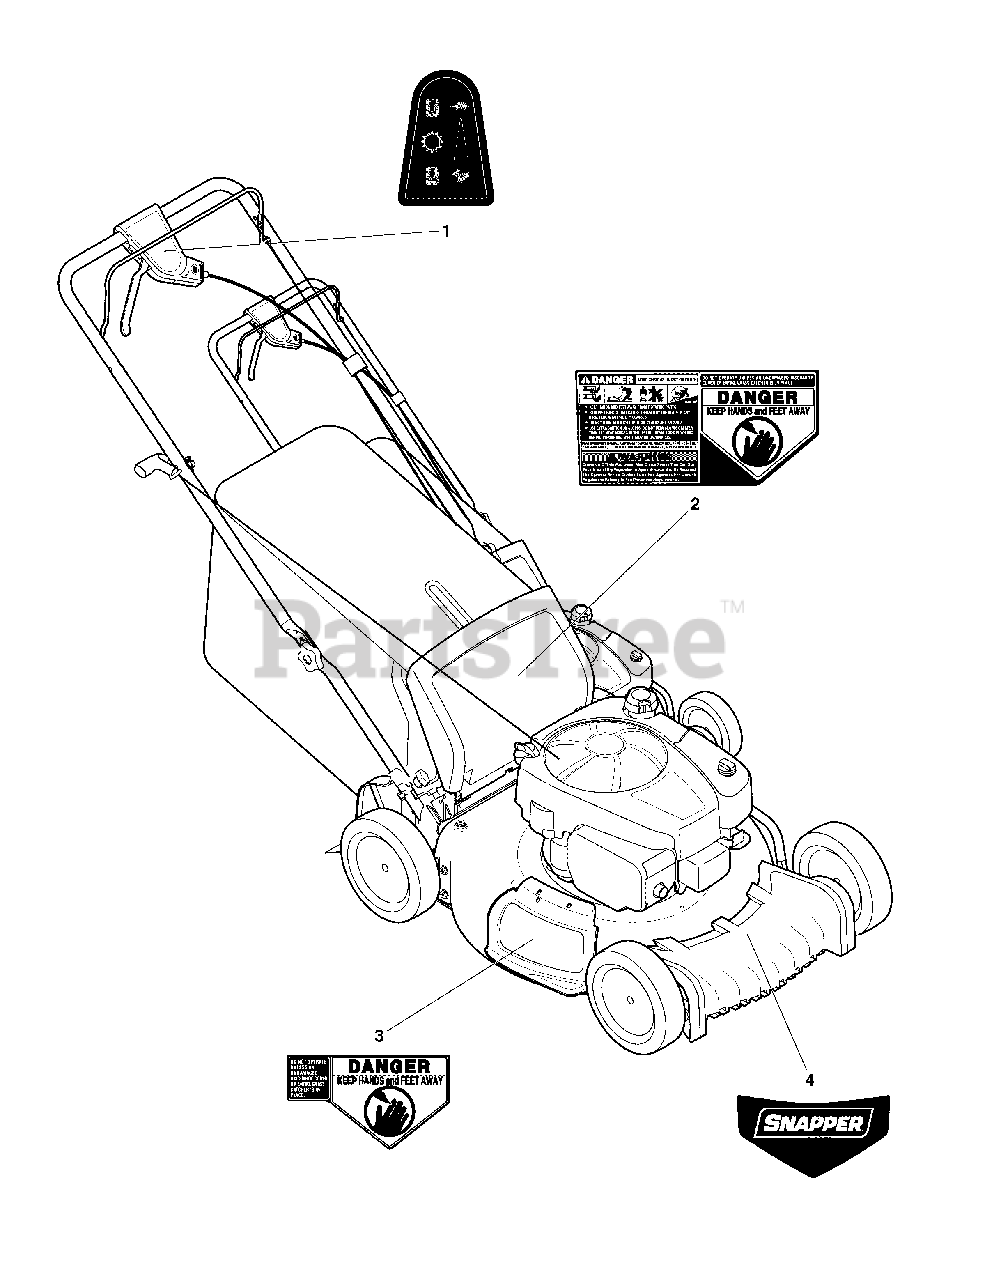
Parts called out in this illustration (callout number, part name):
1	DECAL, Controls
2	LABLE, Danger/Instructions
3	LABLE, Danger/Discharge
4	LABLE, Snapper
